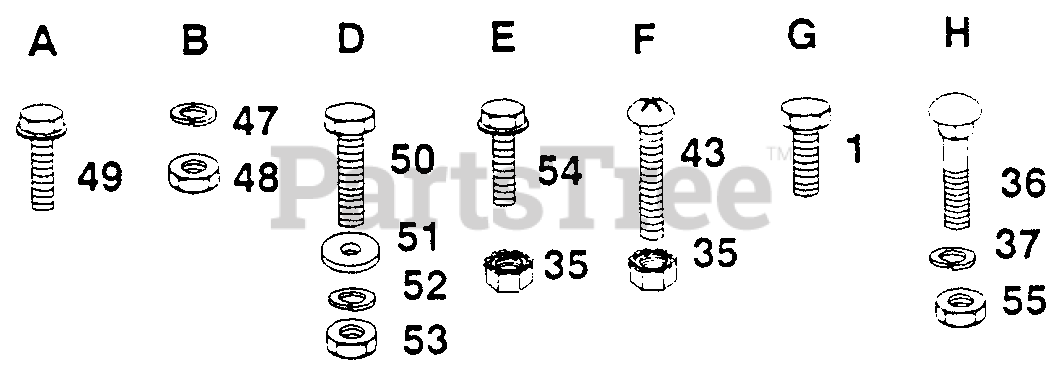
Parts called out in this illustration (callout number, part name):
1	Screw #10-24 x 1/2
35	Nut, Keps #10-32
36	Bolt, Carriage 3/8-16 x 1
37	Washer, Lock 3/8
43	Screw, Slot, Pan HD #10-32 x 1/2
47	Washer, Lock 1/4
48	Nut, Hex Jam 1/4-20
49	Screw, Hex Washer Hd. Cutting 1/4-20 x 1/2
50	Bolt, Hex Hd. 1/4-20 x 3/4
51	Washer 9/32 x 5/8 x 16 Gauge
52	Washer, Lock 1/4
53	Nut, Hex 1/4-20
54	Screw, Hex Washer Hd. # 10-32 x 1-1/2
55	Nut, Fin Hex 3/8-16
